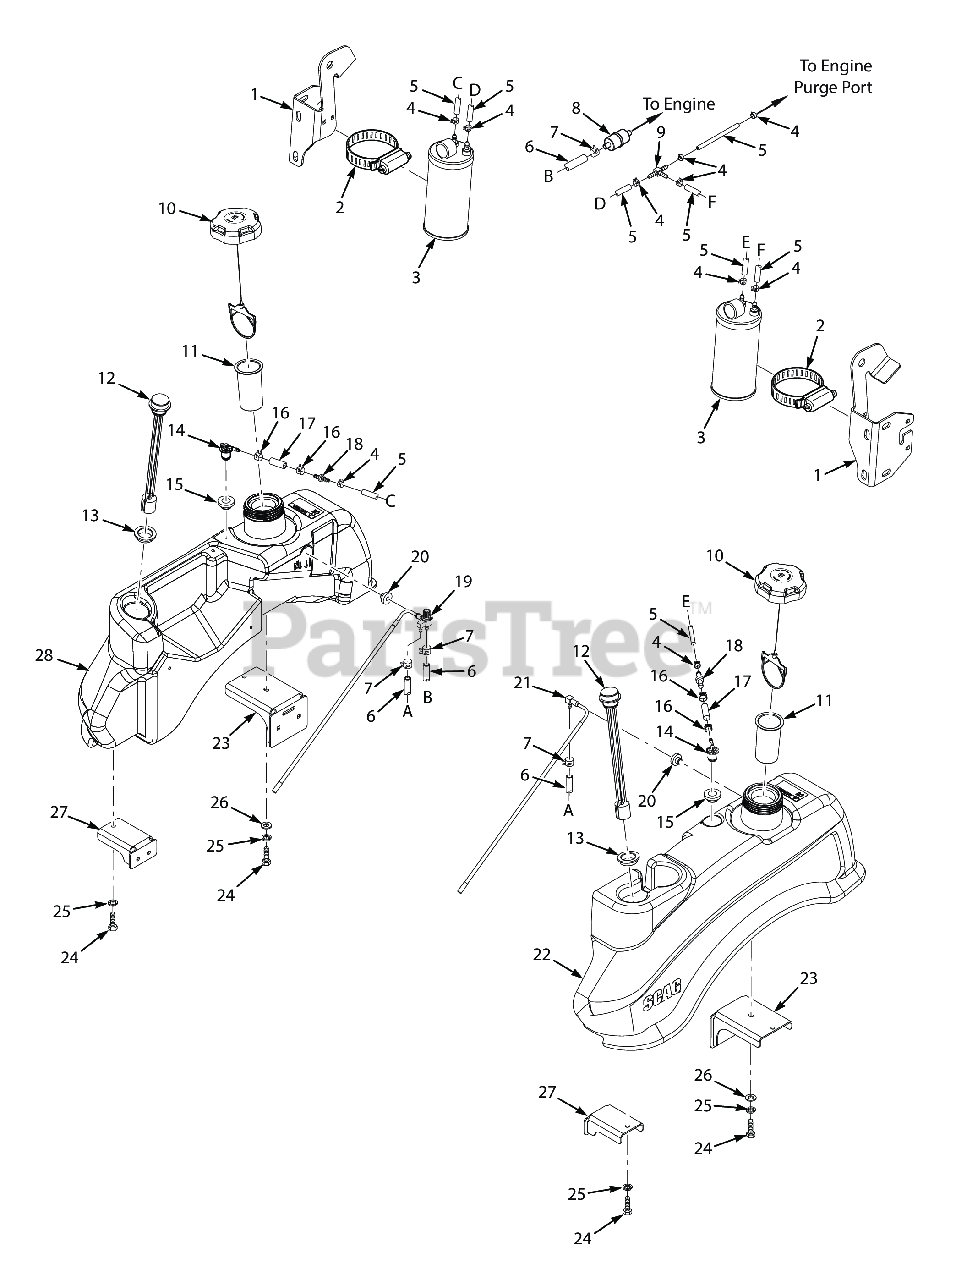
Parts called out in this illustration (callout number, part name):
1	ROPS Mount, LH
1	ROPS Mount, LH, 29CV-EFI
1	ROPS Mount, RH
1	ROPS Mount, RH, 29CV-EFI
2	Clamp, 3-1/2" Max. Dia.
3	Carbon Canister - SVR-36A / SVR-48V
3	Dust Filter, Carbon Canister
4	Clamp, Vapor Recovery Hose 3/16"
5	Hose, Vapor Recovery 3/16" (order by inch)
6	Fuel Hose, 1/4" I.D. Non-Perm (791DFI Fuel Return) - Order by Inch
7	Clamp, Fuel Hose 1/4" Hose I.D.
8	Fuel Filter
9	Tee, 3/16 x 3/16 x 3/16 Union, Hose Barb
10	Fuel Cap w/ Tether (E.P.A.)
10	Fuel Cap w/Tethered - California Models Only
11	Tube, Fuel Tank Insert - 4"
12	Fuel Gauge Assembly
13	Grommet, Fuel Gauge
14	Remote Vent, No Valve
15	Grommet, Viton,
16	CLAMP, FUEL HOSE(KAWASAKI ONLY)
17	Hose, 1/4" Vapor Recovery (order by inch)
18	Mender, 1/4 x 3/16 w/0.02 Hole
19	Fuel Tube Assembly, Includes Valve
20	Bushing, 0.56" Dia. Viton
21	Fuel Tube Assembly, LH
22	Fuel Tank Assembly, LH (incl. # 12, 14, 15, 20, 21)
23	Mounting Bracket, Fuel Tank Rear
24	BOLT, SERRATED FLANGE HEX HEAD 5/16-18 X 3/4"
25	Lockwasher, 5/16 (.317 x .586 x .078) Helical Spring
26	Flatwasher, 5/16-.375 x .875 x .083 (35BV & 37BV-EFI)
27	Mounting Bracket, Fuel Tank Front
28	Fuel Tank Assembly, RH (incl. #12, 14, 15, 19, 20)
